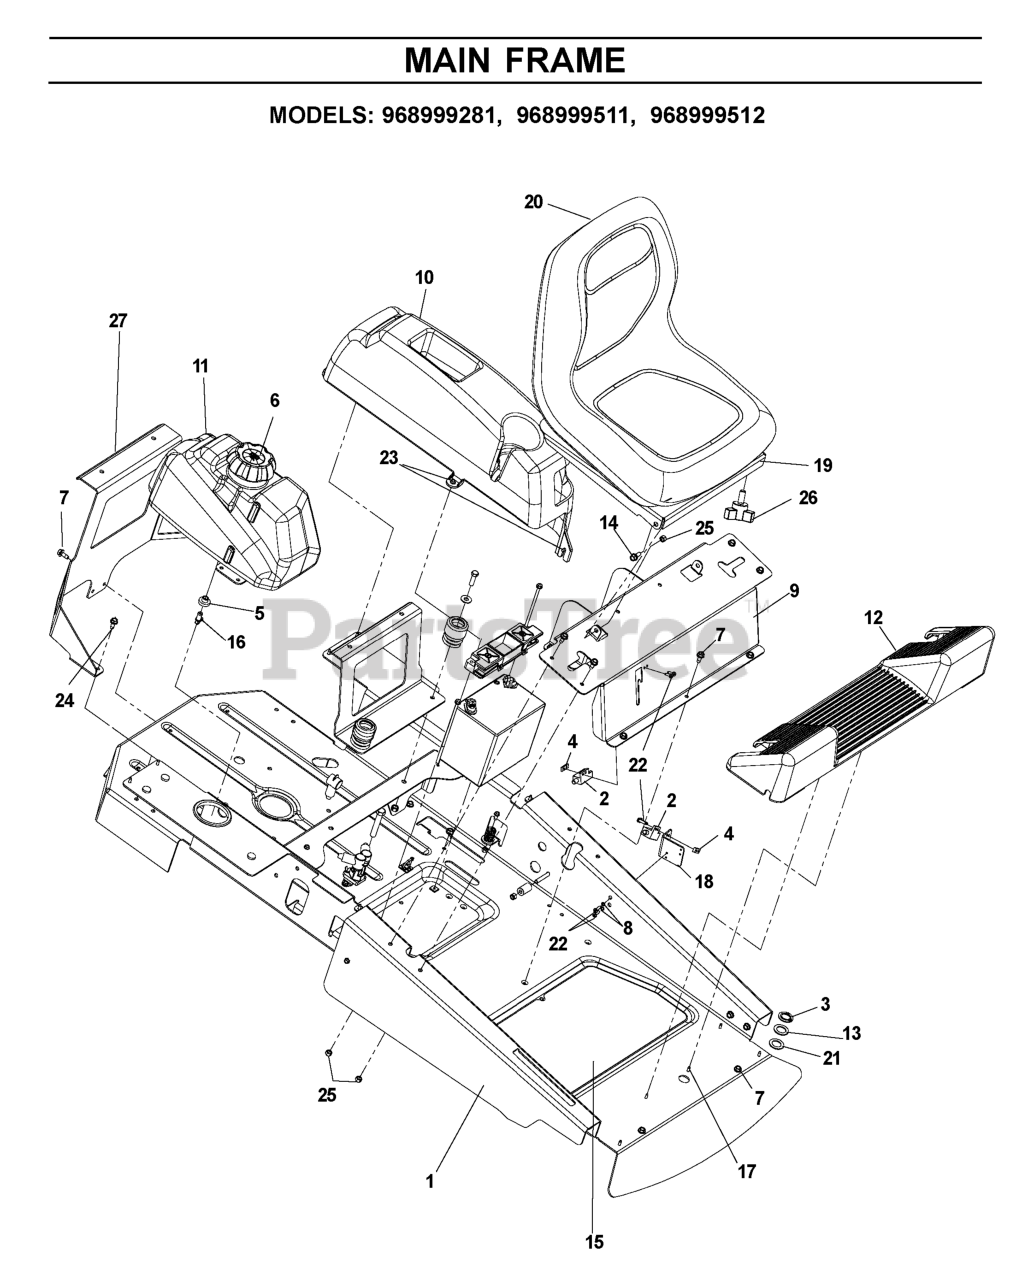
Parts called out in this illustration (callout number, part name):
1	CHASSIS W/DECALS
2	SWITCH, INTERLOCK
3	RETAINING RING, 7/8"
4	TAPPED PLATE
5	RUBBER GROMMET
6	FUEL CAP ANTI-SPLASH
7	BOLT 5/16-18 X 3/4
8	WASHER - 3/16 LOCK ZD
9	CONSOLE
10	FENDER LEFT
12	FOOT REST GRAY
14	BOLT, SHOULDER
15	SLIP, MATTING
16	STEM, FUEL TANK
17	SCR #10-12X3/4 HEX WAS HD ZD
19	SEAT MOUNT, BLACK
20	SEAT.XH150.LOWBACK.GREY.ZTR
21	BSHG .875 X 1.375 X .074 ZD
22	SCREW #10-24 X 5/8
23	SCREW 1/4 X 5/8
25	NUT 5/16 NYLOC
26	KNOB W/STUD
27	REAR BRKT, TOOL BOX, PAINTED
